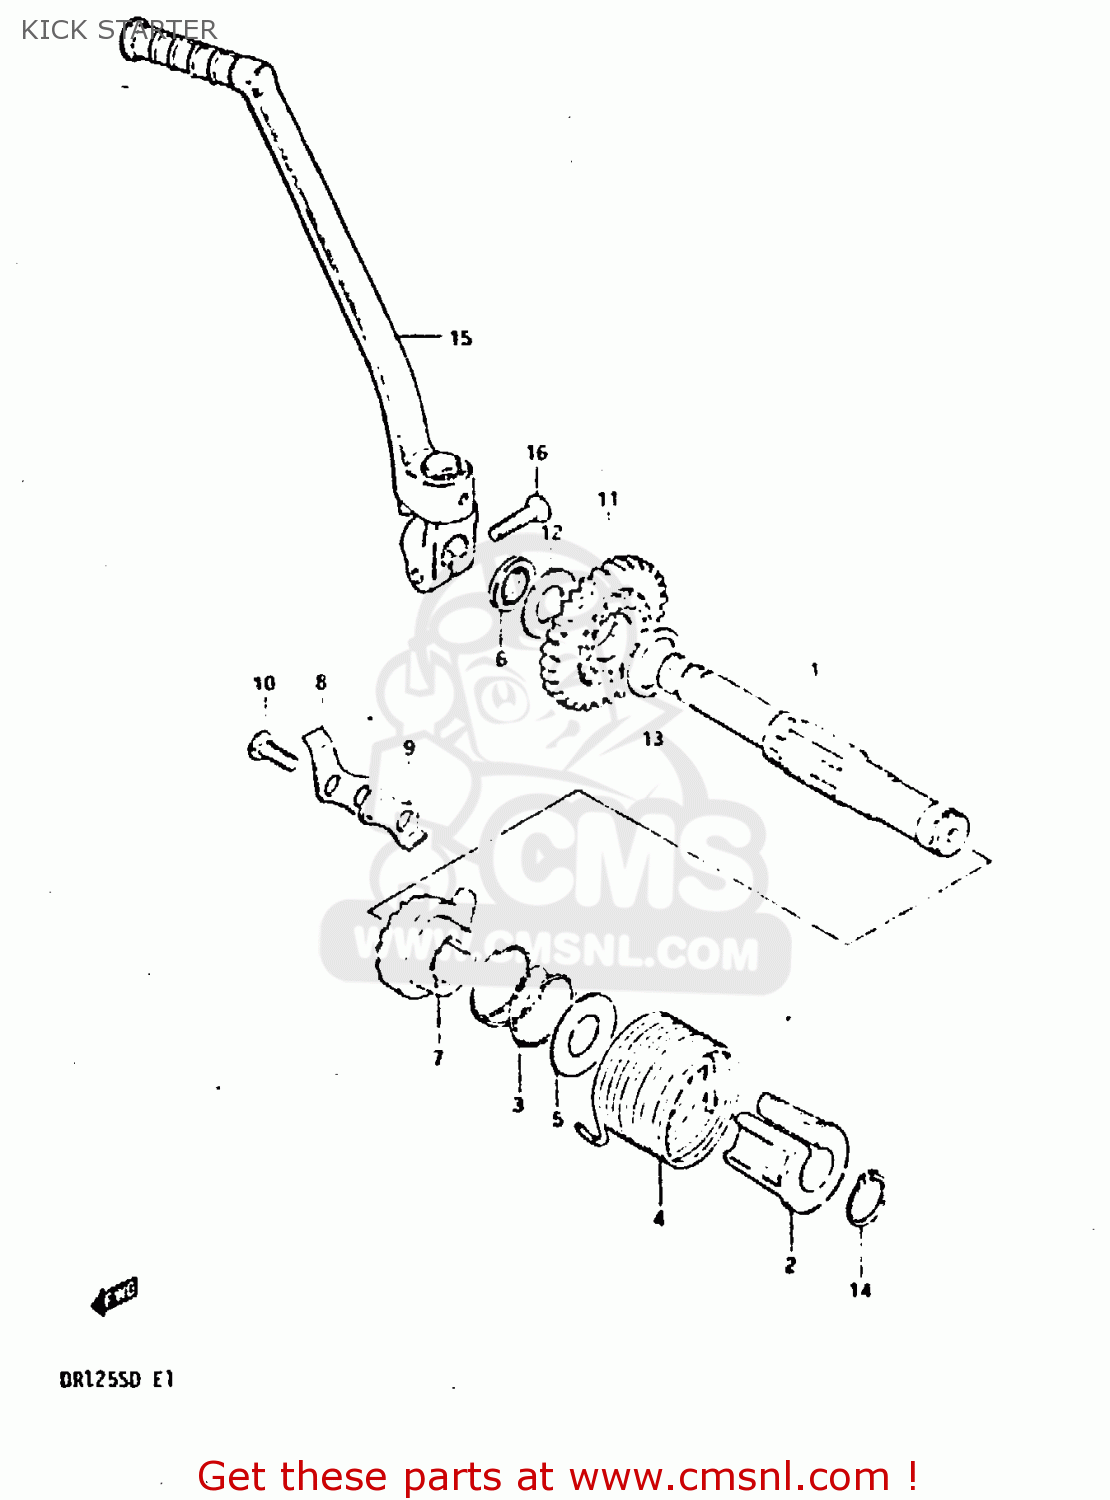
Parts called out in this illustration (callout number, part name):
1	SHAFT,KICK STARTER
2	GUIDE,KICK STARTER SFT SPRING
3	SPRING
4	SPRING
5	WASHER
6	SEAL,OIL(16X24X5)
7	STARTER,KICK
8	GUIDE,KICK STARTER
9	STOPPER,KICK STARTER
10	BOLT
11	GEAR,KICK STARTER DRIVE
12	WASHER(16X30X1)
13	WASHER
14	CIRCLIP
15	LEVER ASSEMBLY,KICK STARTER
16	BOLT 8X25
